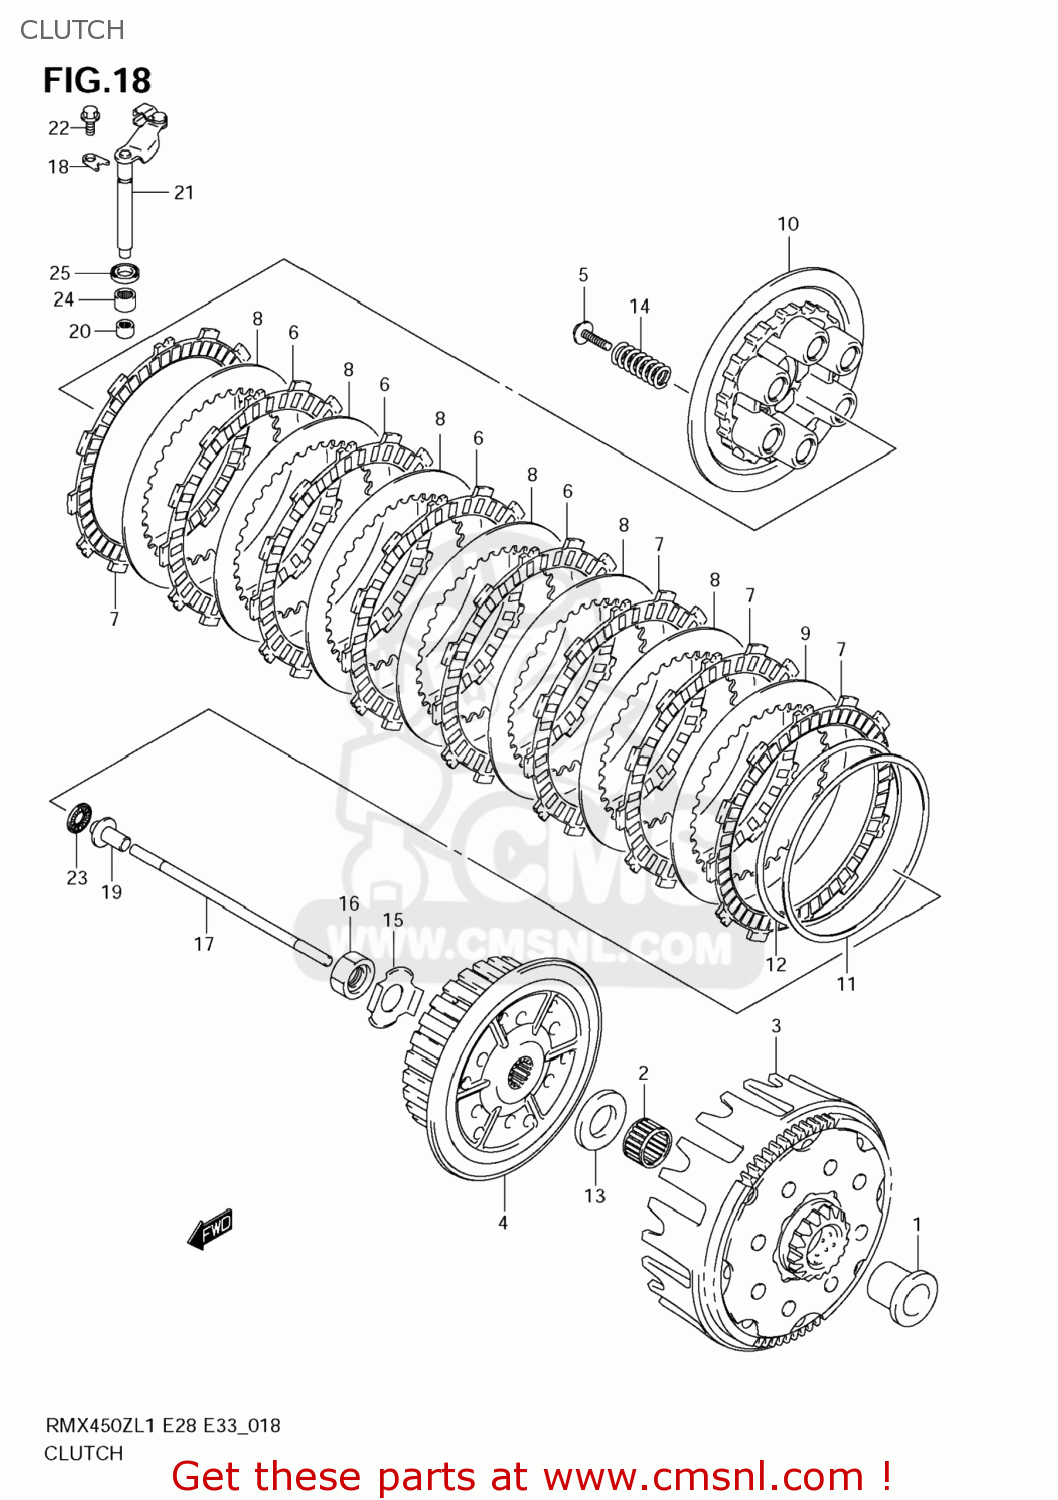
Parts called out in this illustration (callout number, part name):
1	SPACER,PRIMARY DRIVEN GEAR
2	BEARING(28X32X26)
3	GEAR ASSY,PRI DRIVEN
4	HUB,CLUTCH SLEEVE
5	BOLT,CLUTCH SPRING(6X25)
6	PLATE,CLUTCH DRIVE NO.1 (NAS)
7	PLATE,CLUTCH DRIVE NO.2 (NAS)
8	PLATE,CLUTCH DRIVEN (NAS)
9	PLATE,CLUTCH DRIVEN (NAS)
10	DISC,CLUTCH PRESSURE
11	SEAT,WAVE WASHER
12	WASHER,CLUTCH PLATE WAVE
13	WASHER(22.5X39X3)
14	SPRING
15	WASHER,CLUTCH SLEEVE HUB LOCK
16	NUT
17	ROD,CLUTCH PUSH
18	RETAINER,CL RELEASE CAMSHAFT
19	PIECE,CLUTCH PUSH
20	BEARING,CLUTCH RELEASE(7X11X9)
21	CAMSHAFT,CLUTCH RELEASE
22	BOLT(6X12)
23	BEARING(10X22X2.8)
24	BEARING(10X14X10)
25	SEAL,OIL(10X17X5)
